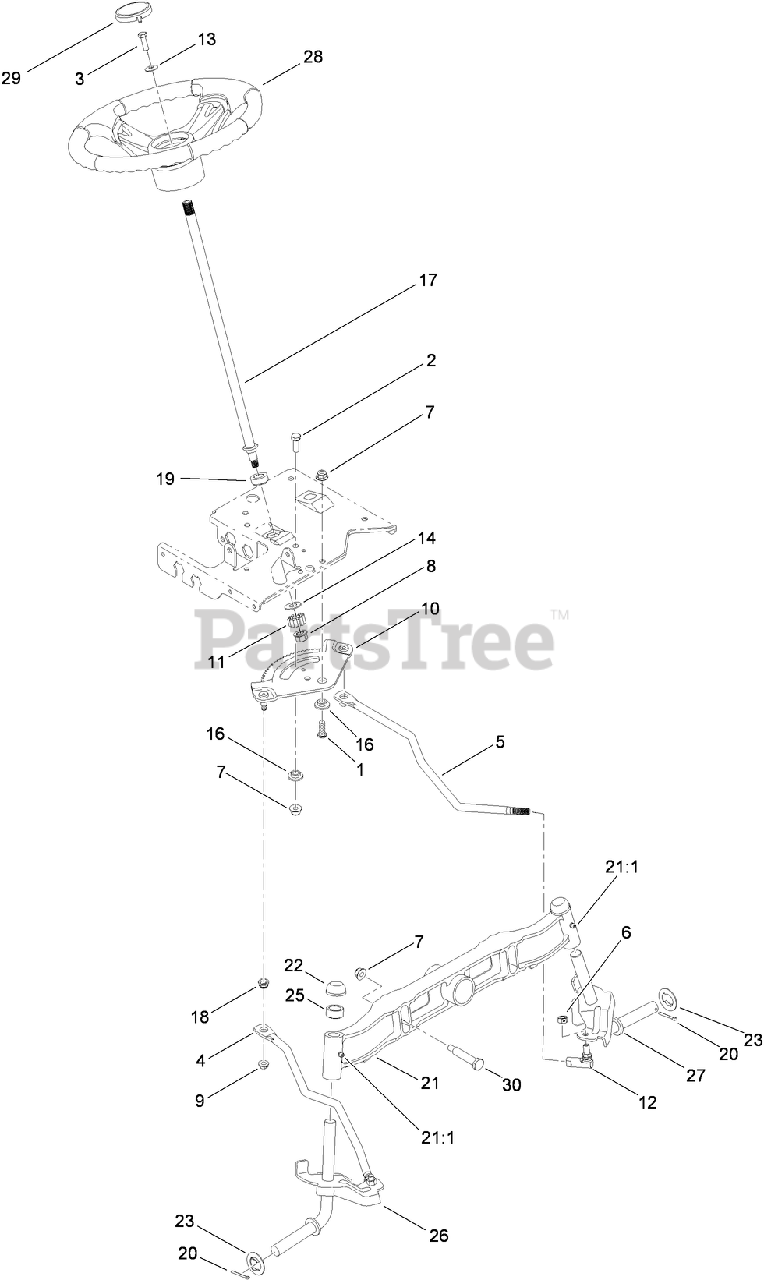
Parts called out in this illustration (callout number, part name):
1	SCREW-HH
2	SCREW-HH
3	SCREW-HH
4	LINK-DRAG, RH
5	LINK-DRAG, LH
6	NUT-HEX, LOCK
7	NUT-LOCK, FLANGE
8	NUT-LOCK, FLANGE
9	NUT-LOCK, FLANGE
11	GEAR-PINION, STEERING
12	BALL JOINT ASM
13	WASHER-FLAT
14	WASHER-FLAT
16	SPACER-SHOULDER
17	SHAFT-STEERING
18	BUSHING
19	BEARING-FLANGE, HEX
20	PIN-COTTER
21	PIVOT-AXLE, CAST IRON
21:1	FITTING-GREASE
23	WASHER-FLAT
25	SPACER
26	RH AXLE ASM
27	LH AXLE ASM
28	3 SPOKE WHEEL STEERING ASM
29	CAP-WHEEL, STEERING
30	BOLT-SHOULDER
